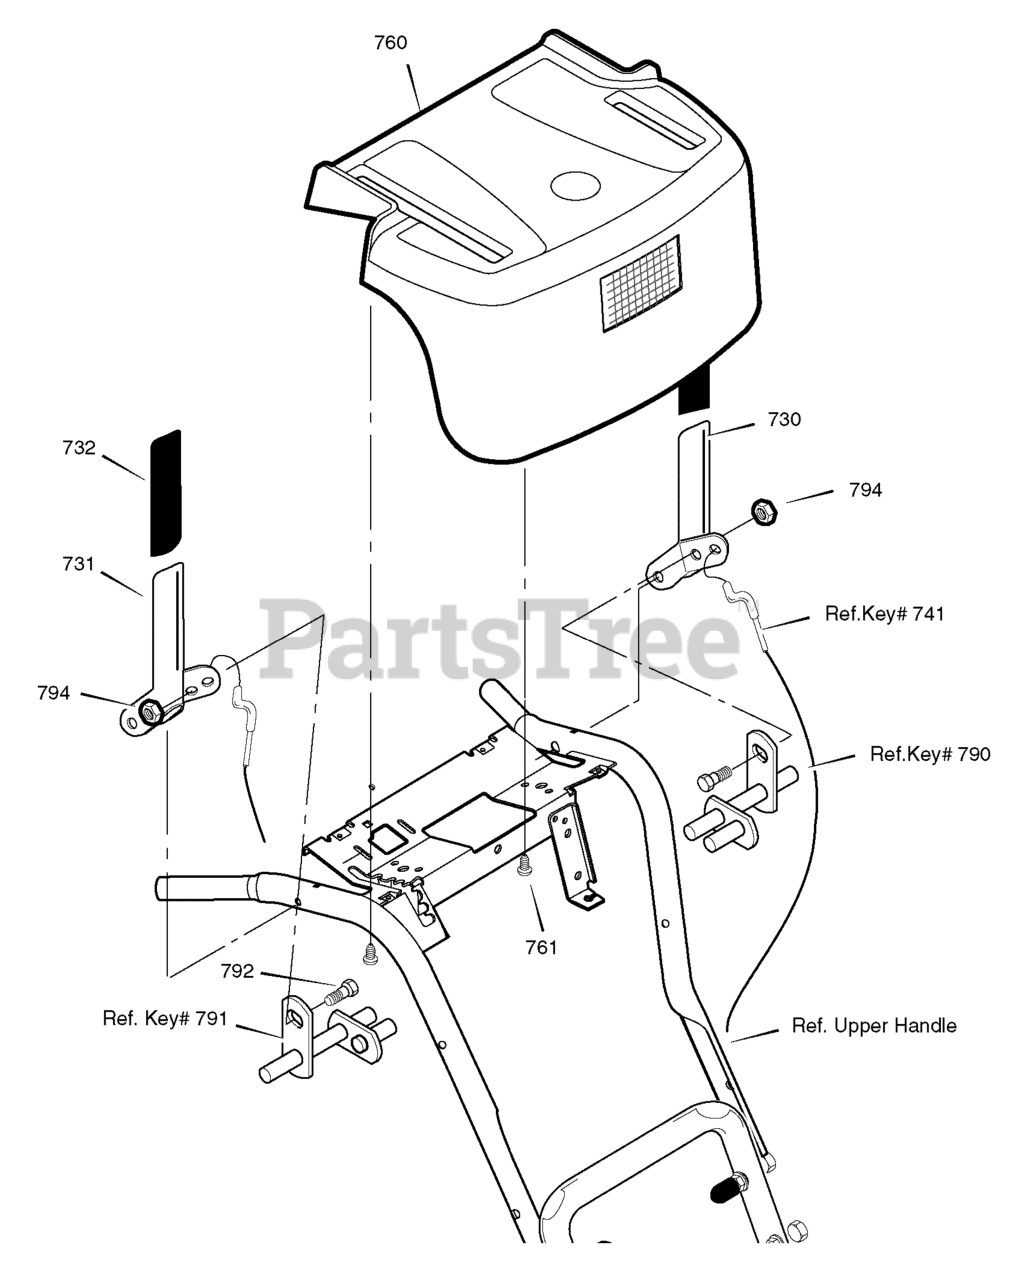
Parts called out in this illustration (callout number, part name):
730	CLUTCH HANDLE LH
731	CLUTCH HANDLE RH
732	GRIP, CLUTCH LEVER
760	PANEL, CONTROL W/LIGHT
792	BOLT, 1/4--20 X 0.50
